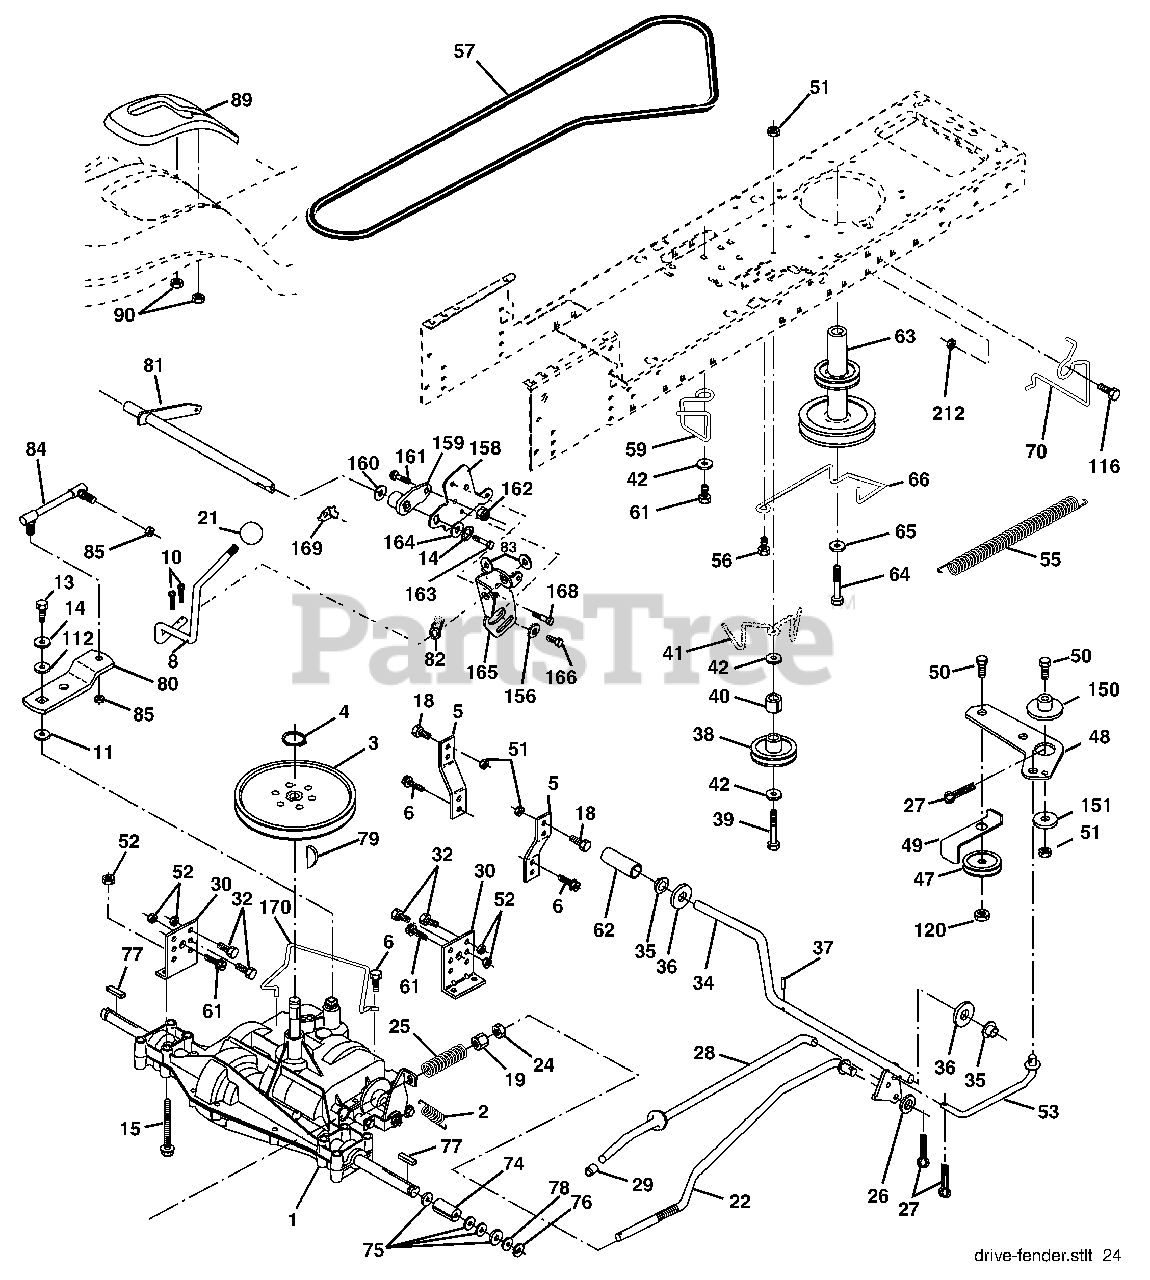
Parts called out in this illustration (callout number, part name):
2	Spring Return Brake T/a Zinc
3	Pulley Transaxle 18" tires
4	Ring Retainer # 5100-62
5	Strap Torque 30 Degrees
6	Screw 5/16-18 x 3/4
8	Rod Shift Fender Adjust Lt
10	Pin Cotter 1/8 x 1 Cad
11	Washer Plate Shf 388 Sq Hole
13	Bolt 1/4-28 Unf Gr 8 W/Patch
14	Washer Lock Hvy Helical
15	Bolt Hex FLGHD 5/16-18 Gr. 5
16	Nut Lock Hex w/ins 5/16-18
18	Bolt, Fin Hex 3/8-16 Unc x 1 Gr. 5
19	Nut Lock 3/8-16 Unc
21	Knob
22	Rod Brake Blk Zinc 26 840
24	Nut Hex Jam 3/8-16 Unc
25	Spring Rod Brake 2 00 Zinc
26	Washer 13/32 x 13/16 x 16 Ga
27	Pin Cotter 1/8 x 3/4 Cad
28	Rod Brake Parking LT/YT
29	Cap Brake Parking
30	Bracket Mtg Transaxle
32	Bolt Hex Hd 5/16-18unc x 3/4
34	Shaft Asm Pedal Foot
35	Bearing Nylon Blk 629 Id
36	Washer 21/32 x 1 x 16 Ga
37	Pin Roll 3/16 x 1"
38	Pulley Composite Flat
39	Bolt Fin Hex 3/8-16 unc x 3
41	Keeper Belt Flat Idler
47	Pulley Idler V Groove Plastic
48	Bellcrank Asm
49	Retainer Belt Style Spring
50	Bolt Carr. Sh. 3/8-16 x 1-1/2 Gr. 5
51	Nut Crownlock 3/8-16 Unc
52	Nut Crownlock 5/16-18 Unc
53	Link Clutch
55	Spring Return Clutch 6 75
56	Screw 3/8-16 x 1-1/4
57	V-Belt Ground Drive
59	Keeper Belt Span Ctr
61	Screw 3/8-16 x .875
62	Cover Pedal Blk Round
63	Engine Pulley
64	Bolt 7/16-20 x 4 x Gr.5
65	Washer Lock Hvy Hlcl Spr 7/16
66	Keeper Belt Engine Foolproof
69	Screw Hex wsh Hi-Lo 1/4 x 1/2 Unc
70	Guide Belt Mower Drive RH
74	Spacer Axle
75	Washer 25/32 x 1 1/4 x 16 Ga
76	E-ring #5133-75
77	Key Square 2 0 x 1845/ 1865
78	Washer 25/32 x 1-5/8 x 16 Ga
79	Key Woodruff #9 3/16 x 3/4
80	Arm Shift
81	Shaft Asm Cross Tapered PMST/20
82	Spring Torsion T/a
83	Washer 17/32 x 3/4 x 16 Ga
84	Link Transaxle
85	Nut Lock Center 1/4 - 28 FNTHD
89	Console Shift STLT
96	Retainer Spring 1"
112	Washer 9/32 x 3/4 x 10 Ga.
113	Strap Torque LT
116	Bolt Rdhd Sq Neck 3/8-16 x 1
120	Nut Lock Flg. 3/8-16 Unc
150	Spacer Retainer
151	Washer 13/32 x 2 x 10
156	Washer Srrted 5/16ID x 1.125
158	Bracket Shift Mount
159	Hub Tapered Flange Shift Lt
161	Bolt Rdhd Sqnk 1/4-20 x 3/4 Gr
162	Nut Crownlock 1/4-20 Unc
163	Bolt Hex Fin 1/4-20 Unc x 1 Gr 5
164	Washer 5/8 x .281 x 10 Ga
165	Bracket Pivot Lever
166	Screw 5/16-18 x 5/8
168	Bolt Shoulder 5/16-18 x .561
169	Plate Fastening
170	Keeper Belt Transaxle Gear
197	Nyliner Snap-In
198	Washer Nyliner
202	Bolt Rd Hd 3/8-16 unc x 1-3/4 Gr.5
212	Nut Hexflange Lock
